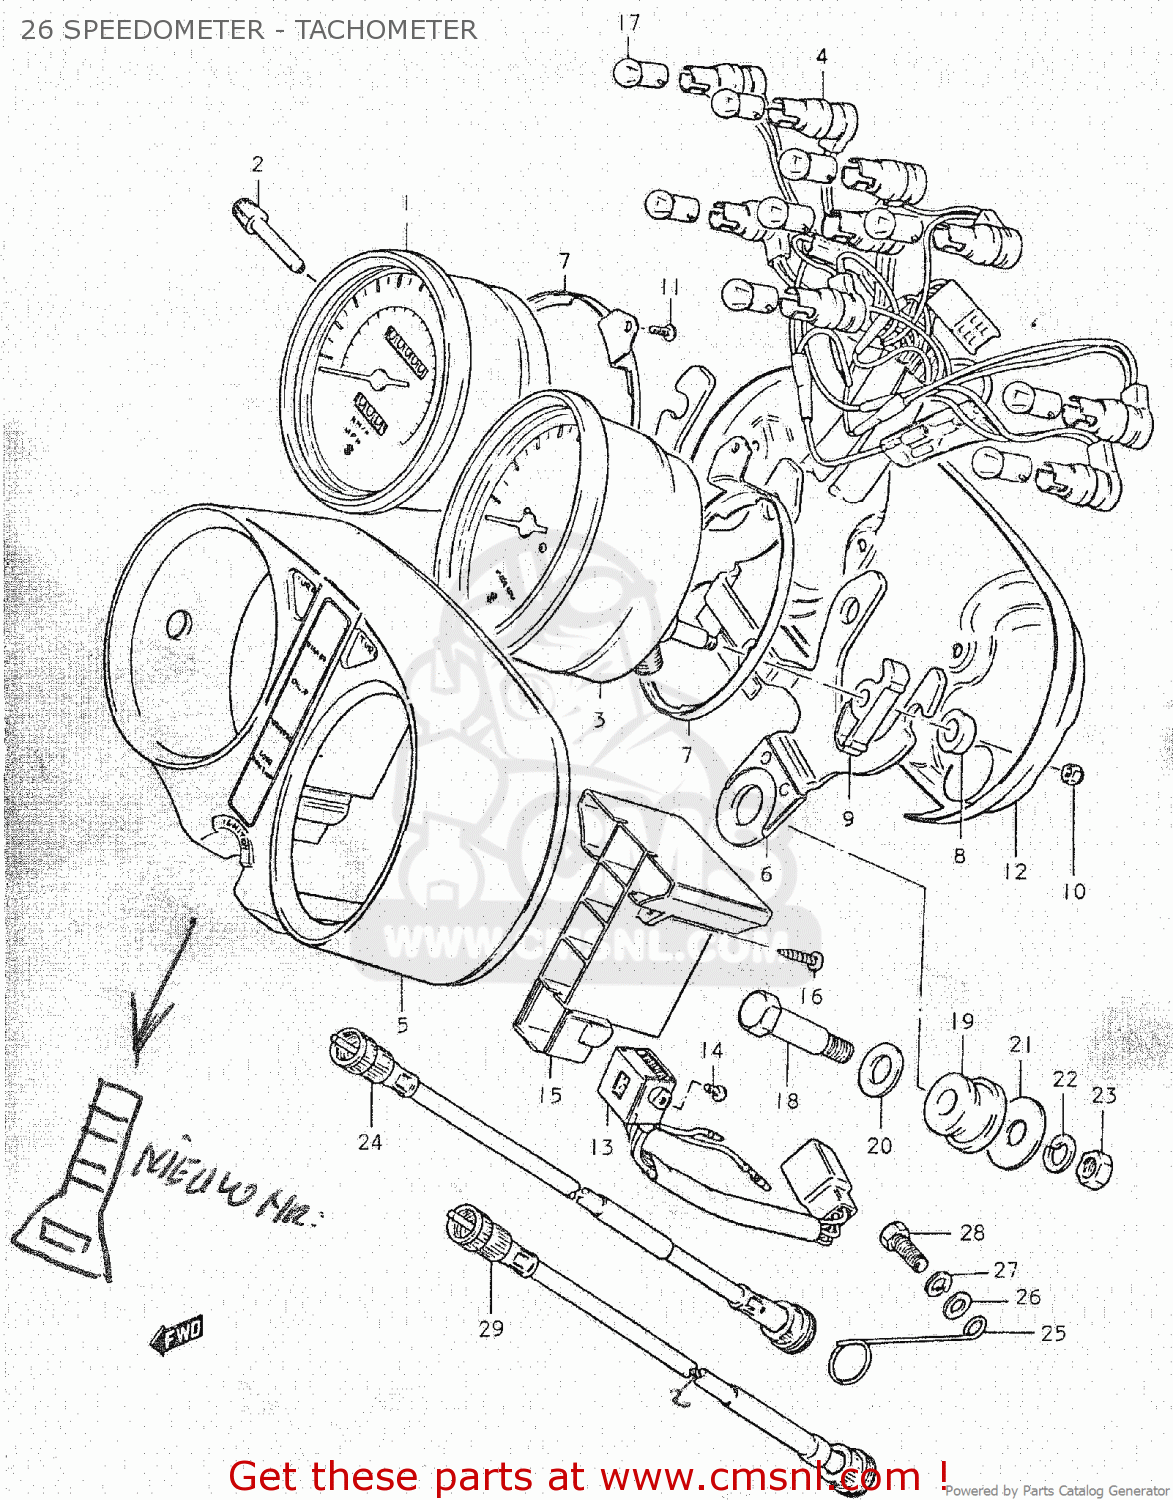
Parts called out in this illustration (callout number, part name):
1	SPEEDOMETER
2	KNOB
3	TACHOMETER
4	SOCKET,METER
5	CASE SET,METER
6	BRACKET,COMBINATION METER
7	PLATE,METER,UNDER
8	CUSHION,METER (A)
9	CUSHION,METER (B)
10	NUT
11	SCREW
12	PLATE,UNDER
13	INDICATOR ASSEMBLY,GEAR POSITION
15	CASE,PILOT BOX,INNER
16	SCREW
17	BULB(12V3.4W,STANLEY,A72A)
18	BOLT(8X31)
19	CUSHION,METER
20	WASHER
21	WASHER (8.5X29X1.6)
22	LOCK WASHER
23	NUT
24	CABLE ASSEMBLY,SPEEDOMETER
25	GUIDE,SPEEDOMETER CABLE
26	WASHER 6MM
27	LOCK WASHER
28	BOLT, UPPER
29	CABLE ASSEMBLY,TACHOMETER
